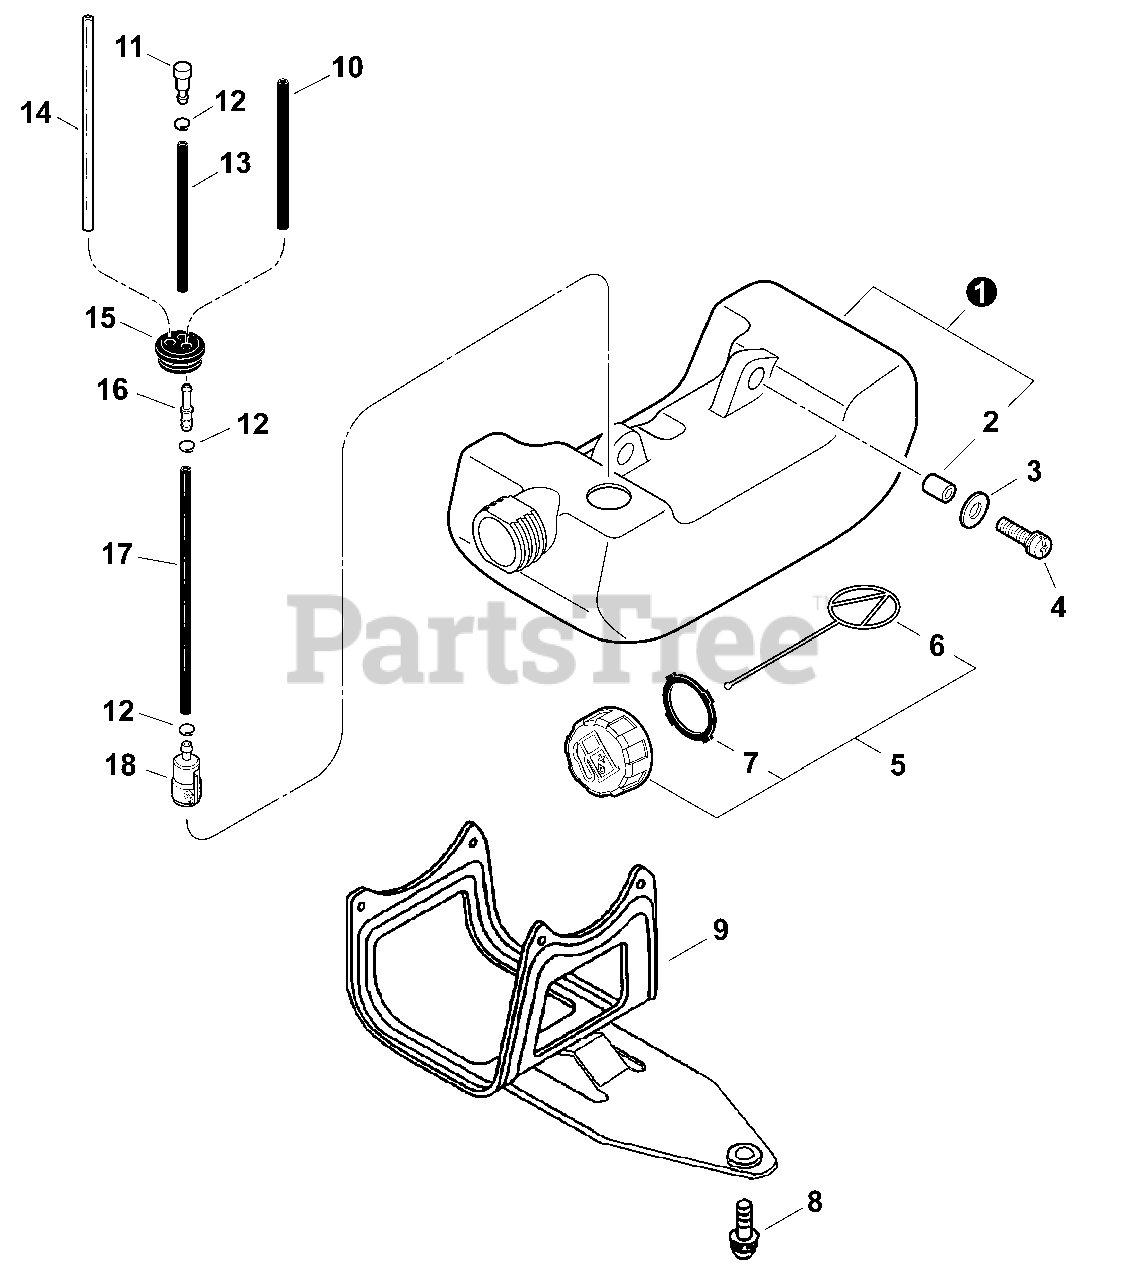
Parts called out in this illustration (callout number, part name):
1	TANK, FUEL
3	WASHER - 5
4	SCREW - 5×16
5	CAP ASY
6	CONNECTOR, CAP
8	SCREW - 5×16
10	PIPE - 3×5×67
11	VENT ASY
13	PIPE, VENT - 3×5×30
14	PIPE, RETURN - 3×6×80
15	GROMMET, FUEL
16	CONNECTOR, FUEL PIPE
17	PIPE - 3×5×110 -- BLACK
18	FILTER, FUEL
